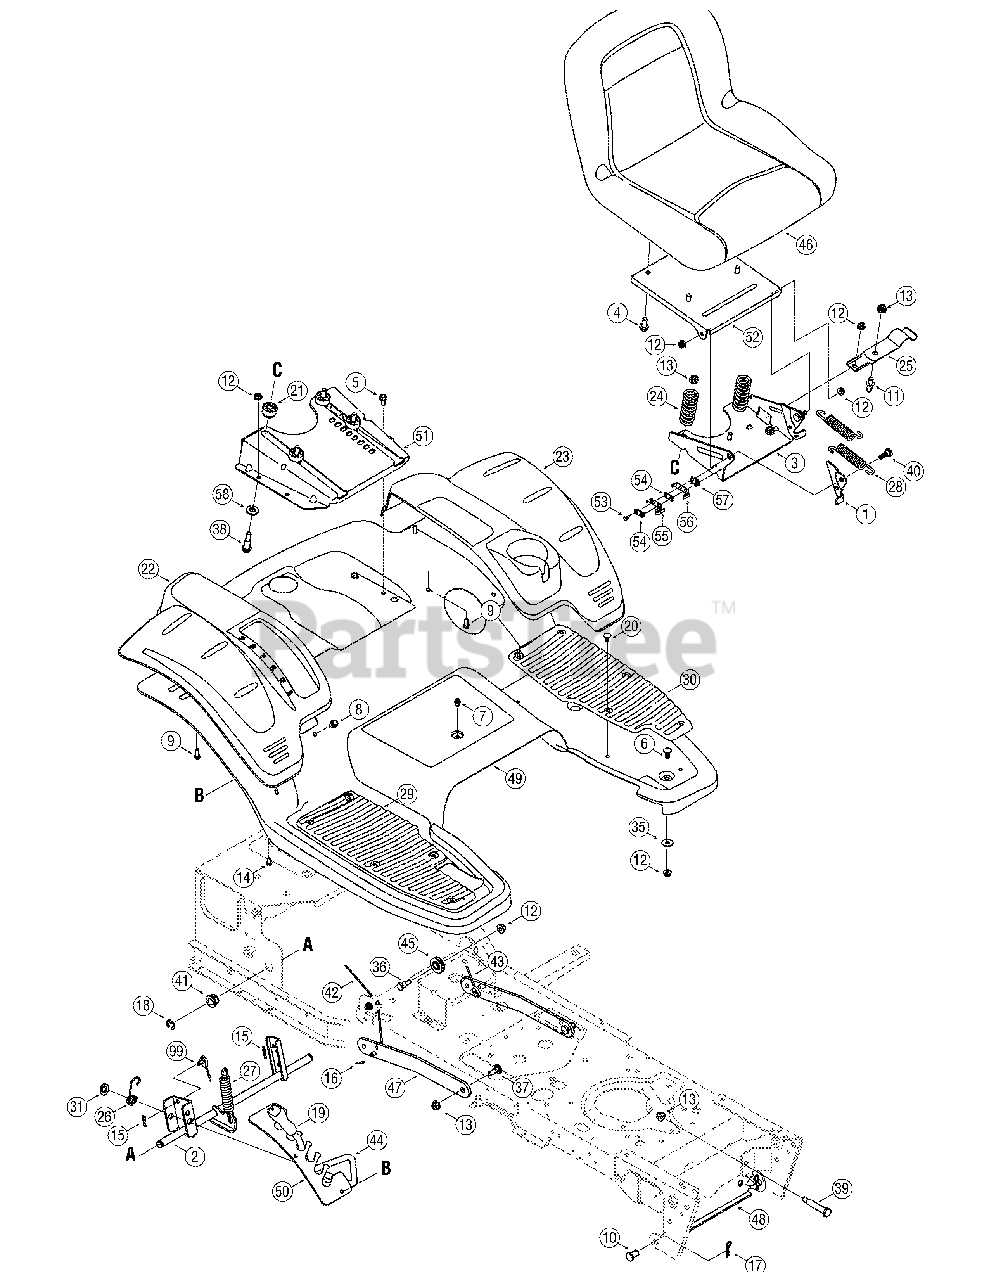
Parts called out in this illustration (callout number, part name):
1	Bracket, RH Seat Lift
4	Screw, Hex Flange, 3/8-16 x .875 Gr5
5	Screw, TT 5/16-18 x .75
6	Screw, Carriage, 5/16-18 x 75
7	Screw, Hex Wash Hd. Tapp, 1/4-20 x .5
8	Screw, Hex Wash Hd. Tapp, 5/16-12 x .75
9	Screw, Hex Wash Hd. Tapp, 1/4-15 x .75
10	Pin, Clevis, .5 x .78
11	Pin, Seat Index
12	Nut, Hex Flange Insert Lock, 5/16-18 GrF
13	Nut, Hex Flange Insert Lock, 3/8-16 GrF
14	Screw, Hex Wash Hd. H/L, 1/4-15 x .5
15	Pin, Internal Cotter
16	Pin, Cotter, 3/32 x 1.0
17	Pin, Internal Cotter
18	E-ring, .625 Shaft
19	Grip, Handle
20	Clip, Ratchet
21	Spacer, Seat Adjustment
22	Cover, Rear Fender RH
23	Cover, Rear Fender LH
24	Spring, Compression
25	Spring, Seat Adjust
26	Spring, Lift Torsion
27	Spring, Extension, .865 x 4.68
28	Spring, Extension, .84 x 4.6
29	Pad, Foot RH
30	Pad, Foot LH
31	Nut, Speed, .5
32	Washer, Flat, .51 x 1.0 x .06
34	Washer, Flat, .535 x .93 x .09
35	Washer, Flat, .344 x 1.0 x .063 HT
36	Bolt, Shoulder, .496 x 2.5:3/8-16
37	Bolt, Shoulder, .5 x .27:3/8-16
38	Bolt, Shoulder, .5 x .925:3/8-16
39	Bolt, Shoulder, .5 x 2.23:3/8-16
40	Bolt, Shoulder, .447 x .268:5/16-18
41	Bearing, Hex Flange,
42	Cable, Lift, 16.16 Lg
43	Cable, Lift, 16.16 Lg
44	Handle, Lift
45	Pulley, Roller
46	Seat, High Back
54	Plate, Insulator
55	Switch, Outer Seat Spring
56	Switch, Inner Seat Spring
57	Plate, Insulator Boss
58	Washer, Flat, .510 x 1 x .125
